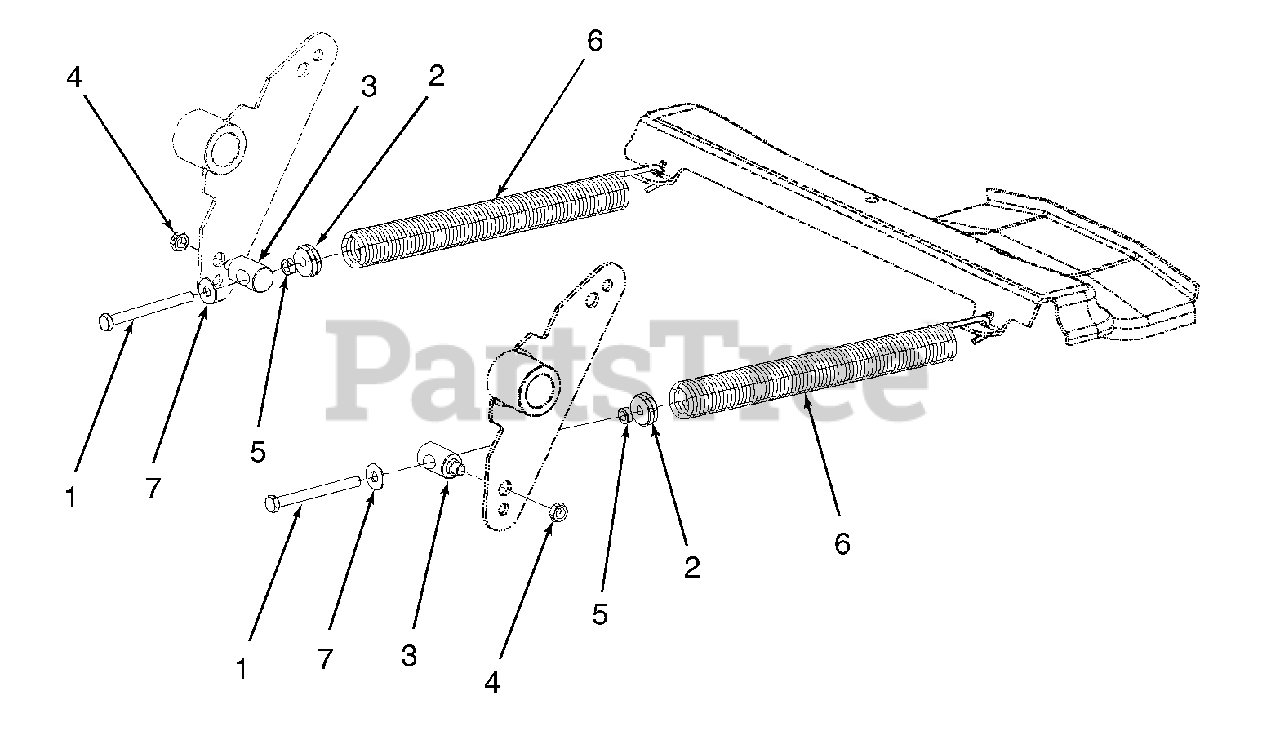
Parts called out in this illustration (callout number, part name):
1	Screw, Hex Cap, Special 5/16-18 x 3.5 GR5
2	Insert, Spring, 5/16-18 Thrd
3	Ferrule, .88 O.D. w/ .160 Dia. Shldr
4	Nut, Hex Center Lock Jam, 3/8-24
5	Nut, Hex Jam, 5/16-18 GR5
6	Spring, Extension, 1.25 O.D. x 11.5
7	Washer, Flat, .349 x .879 x .063
